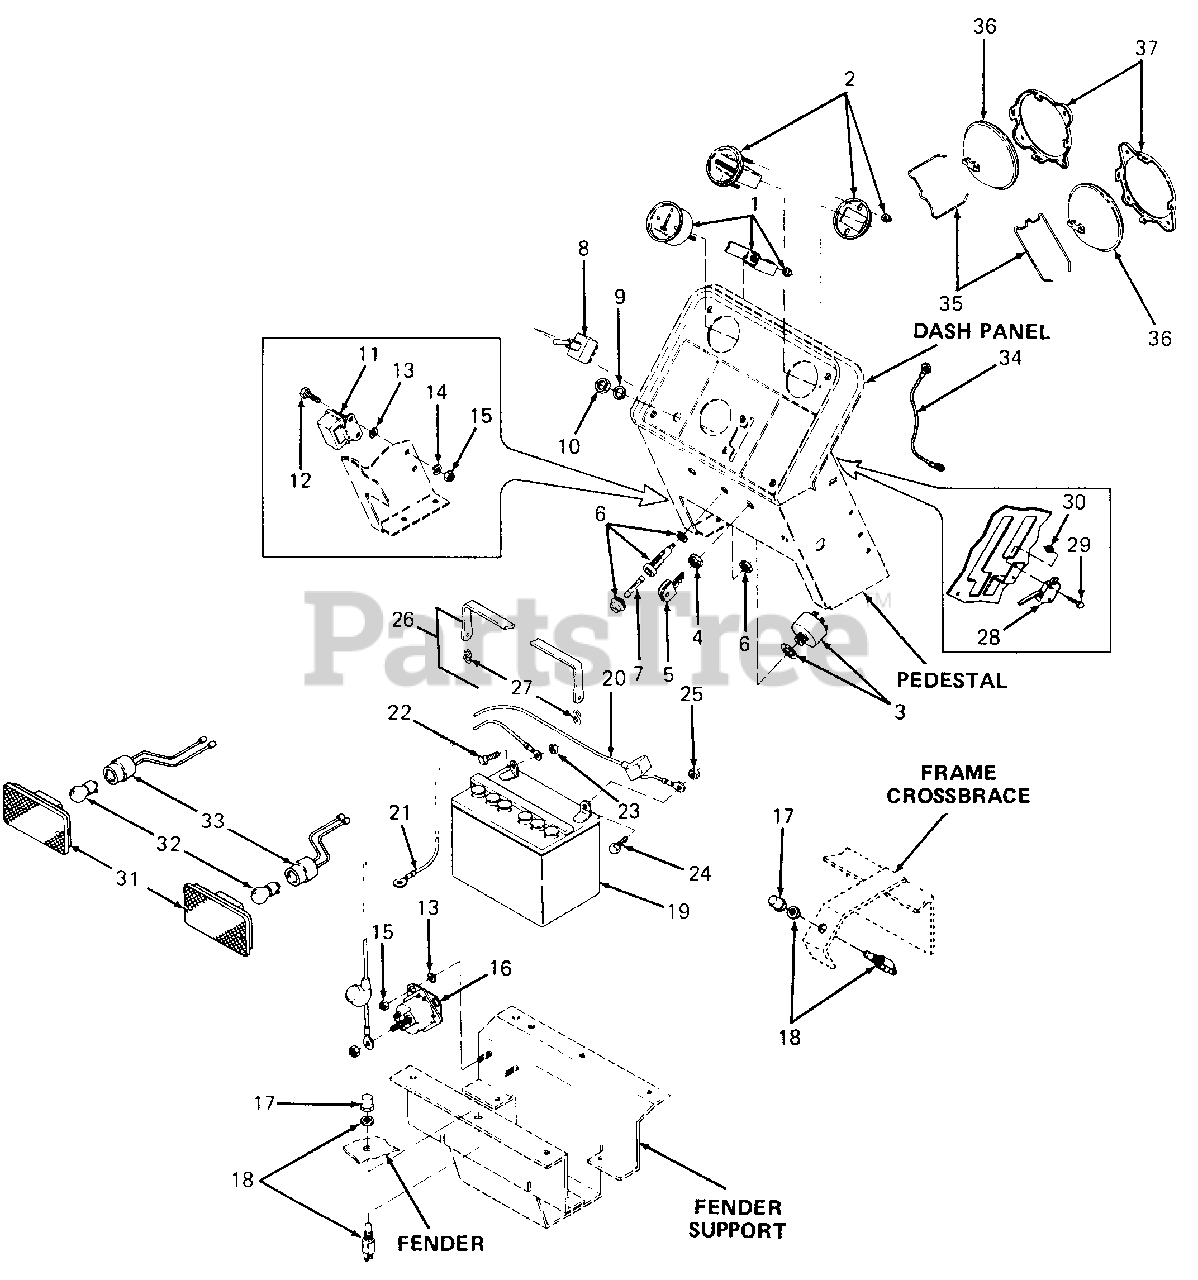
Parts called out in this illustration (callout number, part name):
1	Ammeter
2	Hourmeter
3	Switch, Ignition Key
4	Nut, Switch
5	Key, Ignition (Set of 2)
6	Fuse Holder
7	Fuse, 20 Amp Slo-Blo
8	Switch, PTO
9	Washer, Flat, .531 X .680 X .054 Thk
10	Nut, Hex, 1/2-27 X .100 Thk
11	Relay
12	Screw, Hex Cap, 1/4-20 X .62 Lg GR5
13	Washer, Ext Lock, 1/4
14	Washer, Lock, 1/4
15	Nut, Hex, 1/4-20 GR5
16	Solenoid
17	Boot, Switch
18	Switch w/Nut
19	Battery
20	Cable, Positive Battery
21	Cable, Negative Battery
22	Bolt, Carriage, 1/4-20 X .75 Lg
23	Nut, Hex, 1/4-20 GR5
24	Bolt, Carriage, 5/16-18 X .75 Lg
25	Nut, Hex, 5/16-18 GR5
26	Strap Assy, Battery
27	Hook, Battery Strap
28	Switch, Reverse
29	Screw, Hex Mach, #4-40 X .75 Lg
30	Nut, Hex Insert Lock, #4-40
31	Lens Assy, Tail Light
32	Bulb, Light
33	Cable Assy, Tail Light
34	Cable, Engine Ground
35	Spring, Headlight Retaining
36	Headlights
37	Retainer, Headlight
